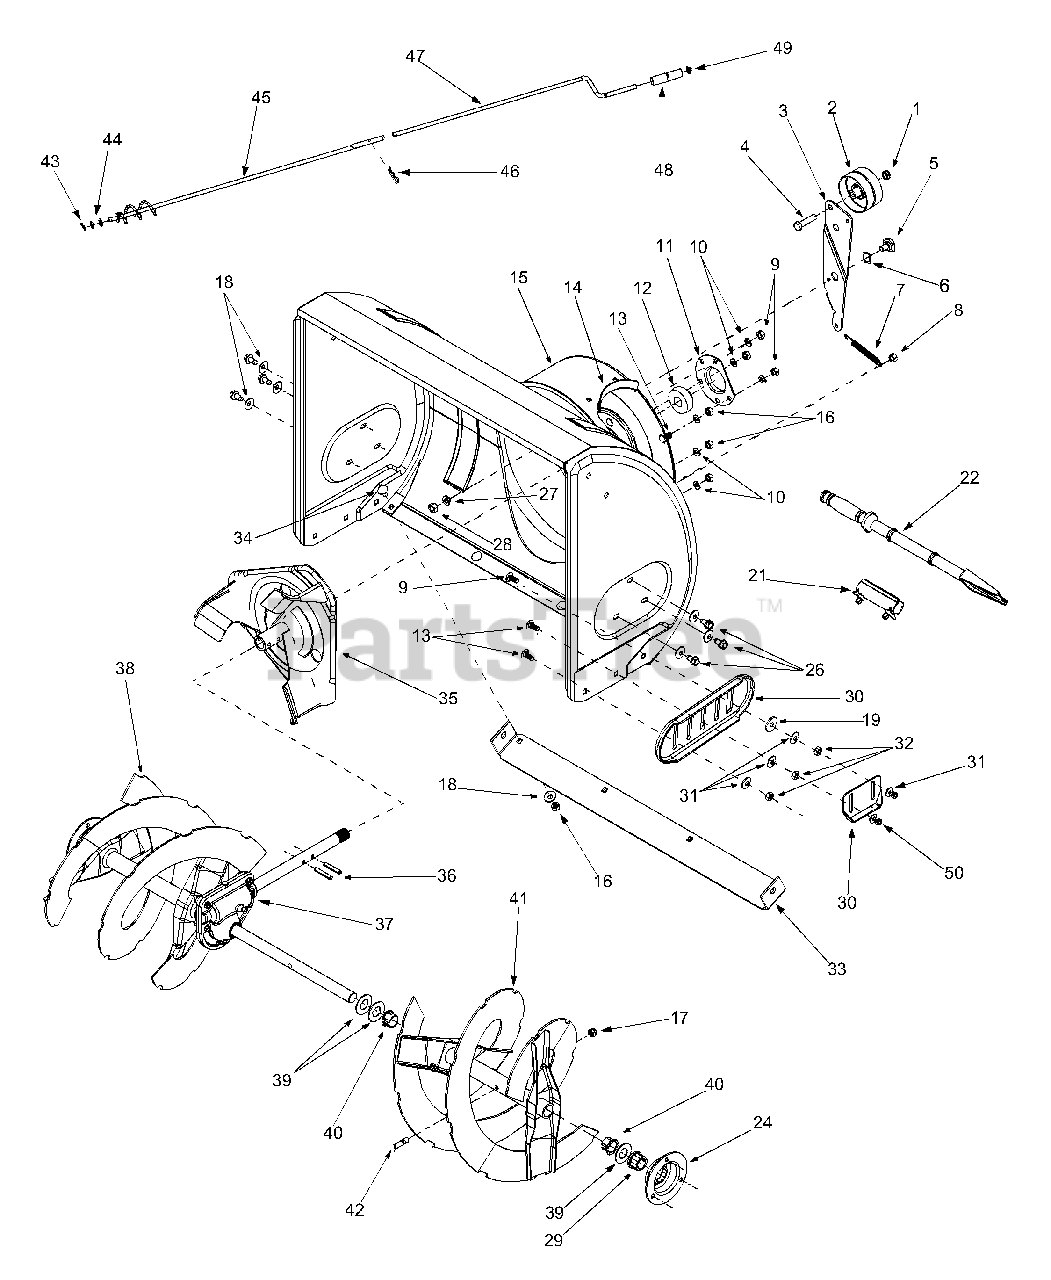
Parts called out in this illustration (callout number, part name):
1	Lock Jam Nut 3/8-24
2	Flat Idler
4	Hex Cap Screw 3/8-24 x 1.50
5	Shoulder Screw
6	Flat Washer .656 ID x 1.25 OD
7	Extension Spring
8	Hex Nut 5/16-18
9	Carriage Bolt, 5/16-18 x 1.00
10	Lock Washer 5/16
11	Housing
12	Ball Bearing
13	Carriage Bolt, 5/16-18 x .75
17	Lock Nut 5/16-18
18	Belleville Washer
19	Flat Wshr, .344ID x 1.125 OD
21	Clean-Out Tool Mount
22	Clean-Out Tool
26	Hex Screw 5/16-18
27	Lock Washer 3/8
28	Hex Nut 3/8-16
29	Hex Flange Bearing
31	Bell Washer
32	Hex Nut 5/16-18
34	Carriage Bolt 5/16-18 x 1.00
37	Gear Assembly Complete, 28"
39	Flat Washer
40	Flange Bushing
42	Shear Bolt 5/16-18 x 1.5
43	Hairpin Clip
44	Flat Washer
48	Chute Crank Knob
49	Push Cap
50	Hex Nut 5/16-18
